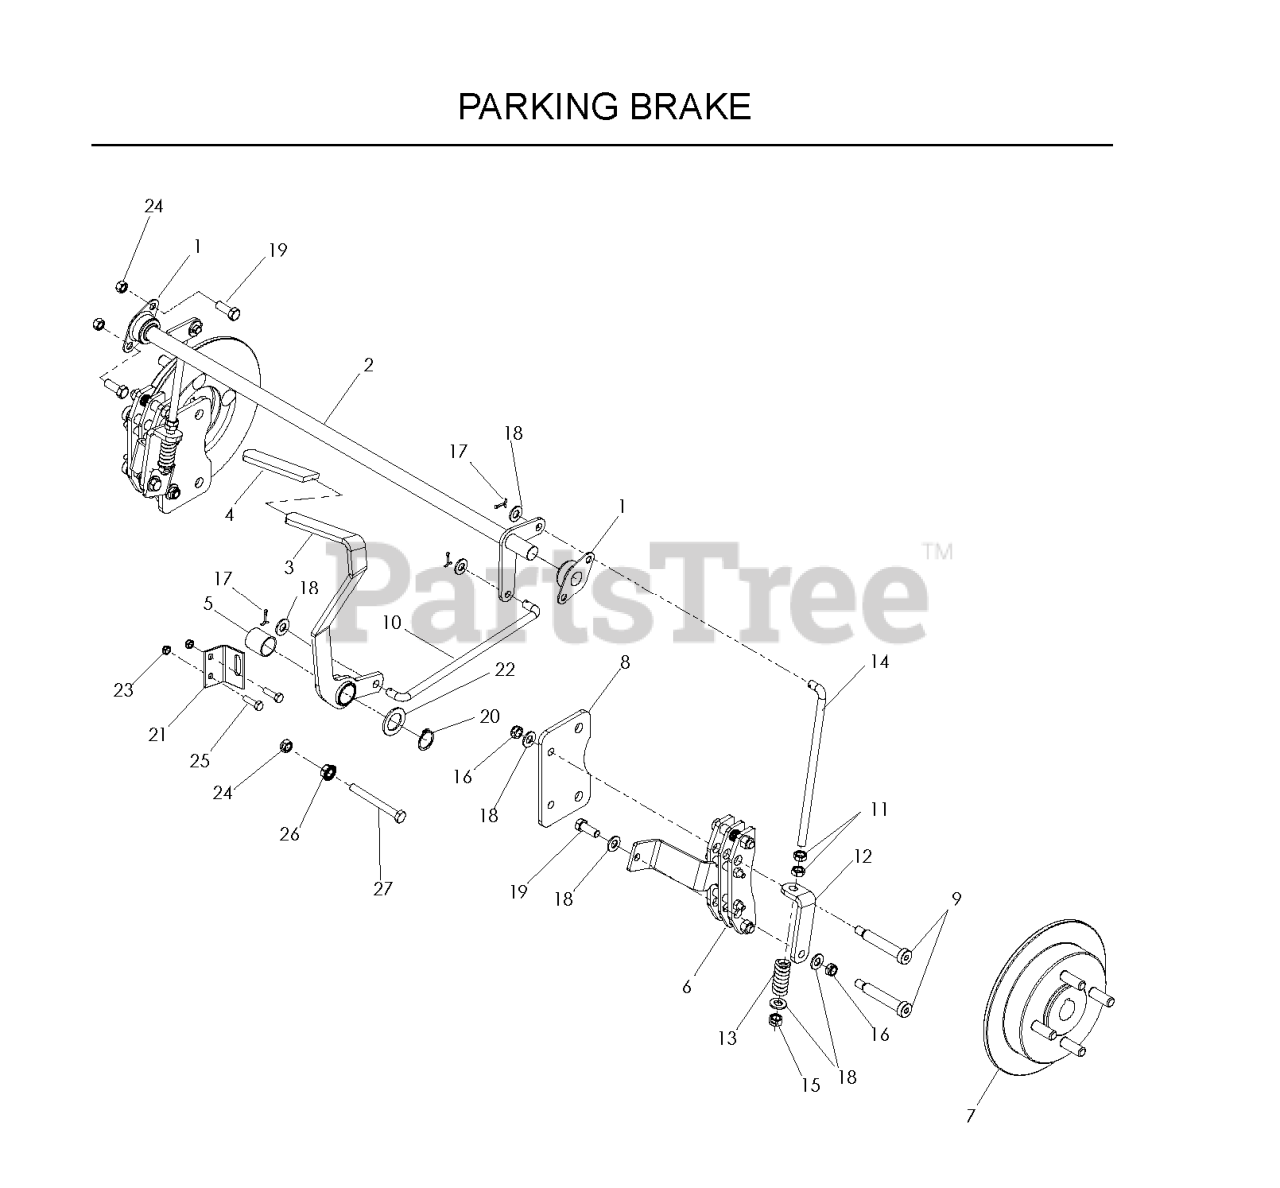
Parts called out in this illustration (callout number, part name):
1	FLANGE BEARING
2	BRAKE CROSS SHAFT
3	BRAKE LEVER WLDMT
4	GRIP, PARK BRAKE
8	PLATE, BRAKE
9	SB 3/8-16 X 2-1-1/2 SKT HDD ZD
10	LINKAGE, BRAKE
11	NUT 3/8-24 JAM
12	BRACKET, L
14	LINKAGE, REAR BRAKE
15	NUT 3/8F CENTERLOCK
16	NUT HEX 3/8-16 NYLON, THIN
17	COTTER PIN 3/32 X 3/4
18	WASHER 3/8 SAE FLAT
19	HCS 3/8-16X1.GRD.5.ZD
20	RETAINING RING, 7/8"
21	BRACKET, BRAKE SWITCH
22	BSHG .875 X 1.375 X .074 ZD
23	NUT.1/4-20.HEX.NYLOC.ZD
24	NUT 3/8-16 NYLOC
25	HCS 1/4C X 3/4 HCS
26	NUT 3/8C WHIZ
27	HCS 3/8C X 2 1/2
